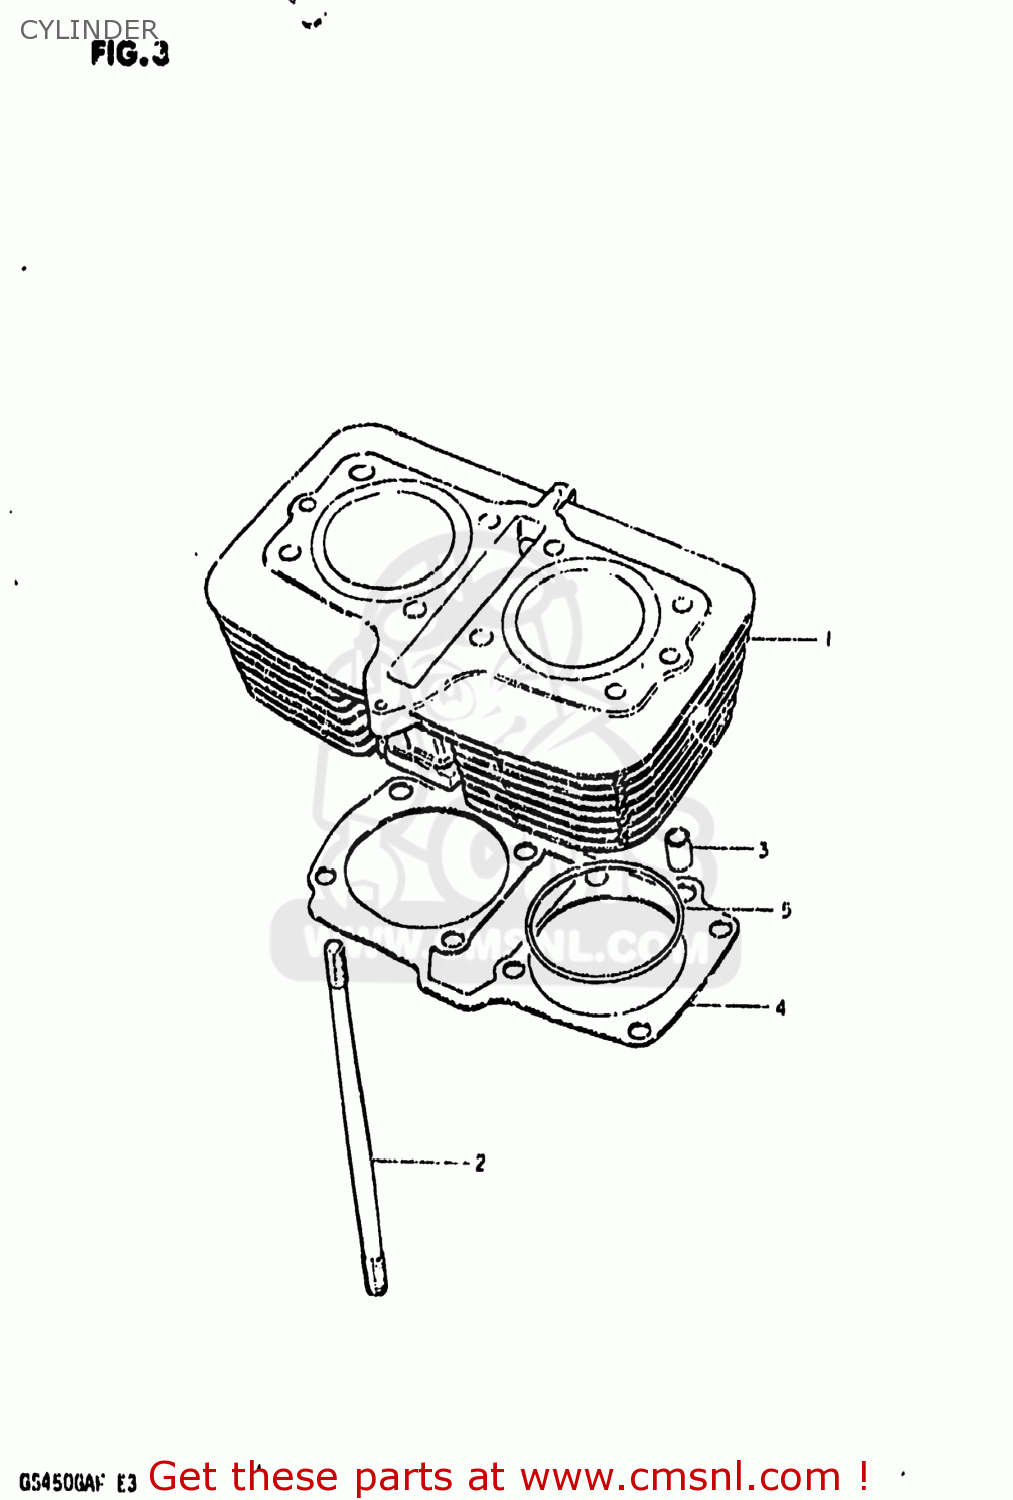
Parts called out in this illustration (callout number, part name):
1	CYLINDER
2	STUD
3	PIN
4	GASKET,CYLINDER (MCA)
5	O RING(D:2,ID:74)
